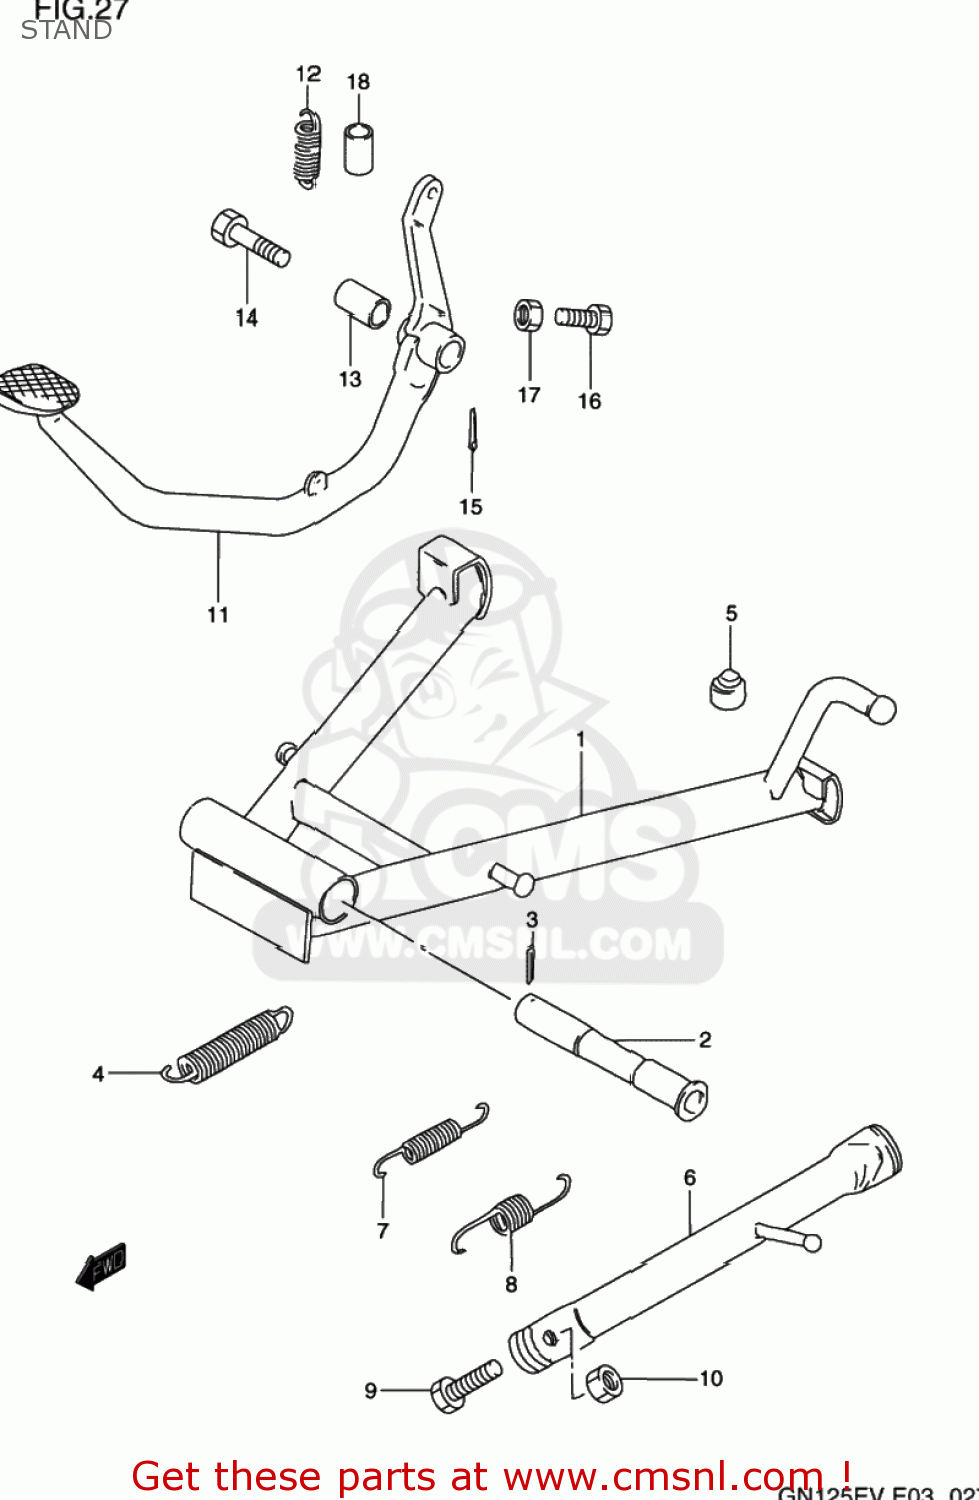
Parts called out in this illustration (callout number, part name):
1	STAND,CTR
2	SHAFT,CTR STAND
3	COTTER PIN
4	SPRING
5	CUSHION
6	STAND,PROP
7	SPRING
8	SPRING
9	BOLT(10X30)
10	NUT
11	PEDAL,BRAKE
12	SPRING
13	SPACER,BRAKE PEDAL BOSS
14	BOLT(10X52)
15	PIN 20X20
16	BOLT(6X23)
17	NUT 6MM
18	TUBE,BRAKE SPRING GUIDE
